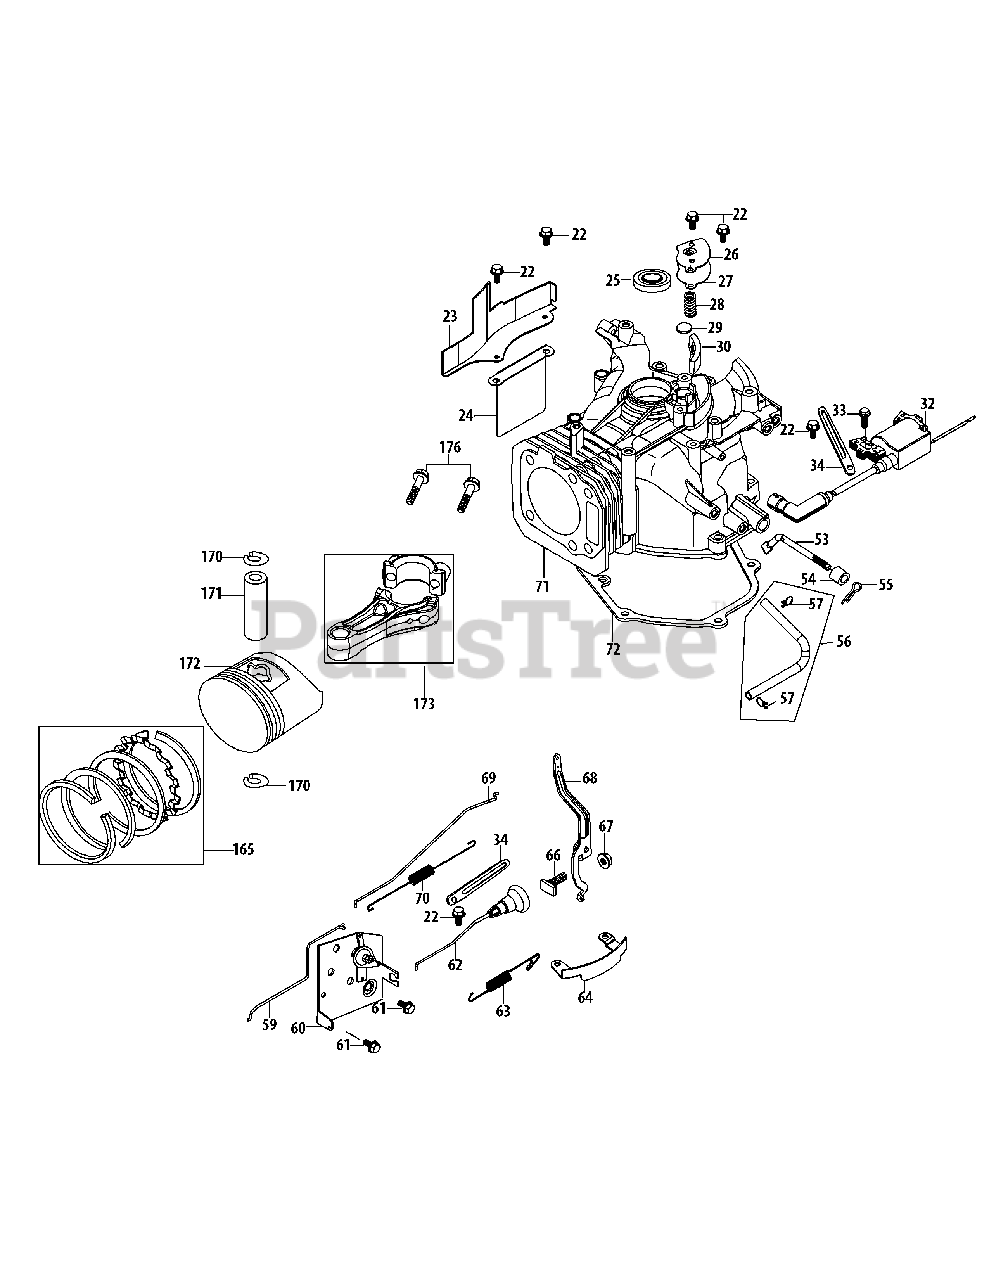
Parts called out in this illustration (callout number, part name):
22	Bolt M6×14
23	Air Guide Bracket
24	Label Bracket
25	Upper Crankshaft Seal
26	Breather Cover Plate
27	Breather Gasket
28	Breather Spring
29	Breather Valve
30	Mesh Screen
32	Ignition Coil Assembly
33	Bolt M6×18
34	Flexible Clamp
53	Governor Arm Shaft
54	Governor Seal
55	Cotter Pin
56	Breather Hose Assembly
57	Breather Hose Clamp
59	Choke Linkage
60	Variable Speed Control Brkt
61	Bolt M6×12
62	Choke Control Knob
63	Governor Spring
64	Governor Arm Shield
66	Governor Arm Bolt
67	Nut M6
68	Governor Arm
69	Throttle Linkage
70	Throttle Linkage Spring
71	Short Block Assembly
72	Crankcase Cover Gasket
165	Piston Ring Set
170	Piston Pin Snap Ring
171	Piston Pin
172	Piston
173	Connecting Rod Assembly
176	Connecting Rod Bolt
